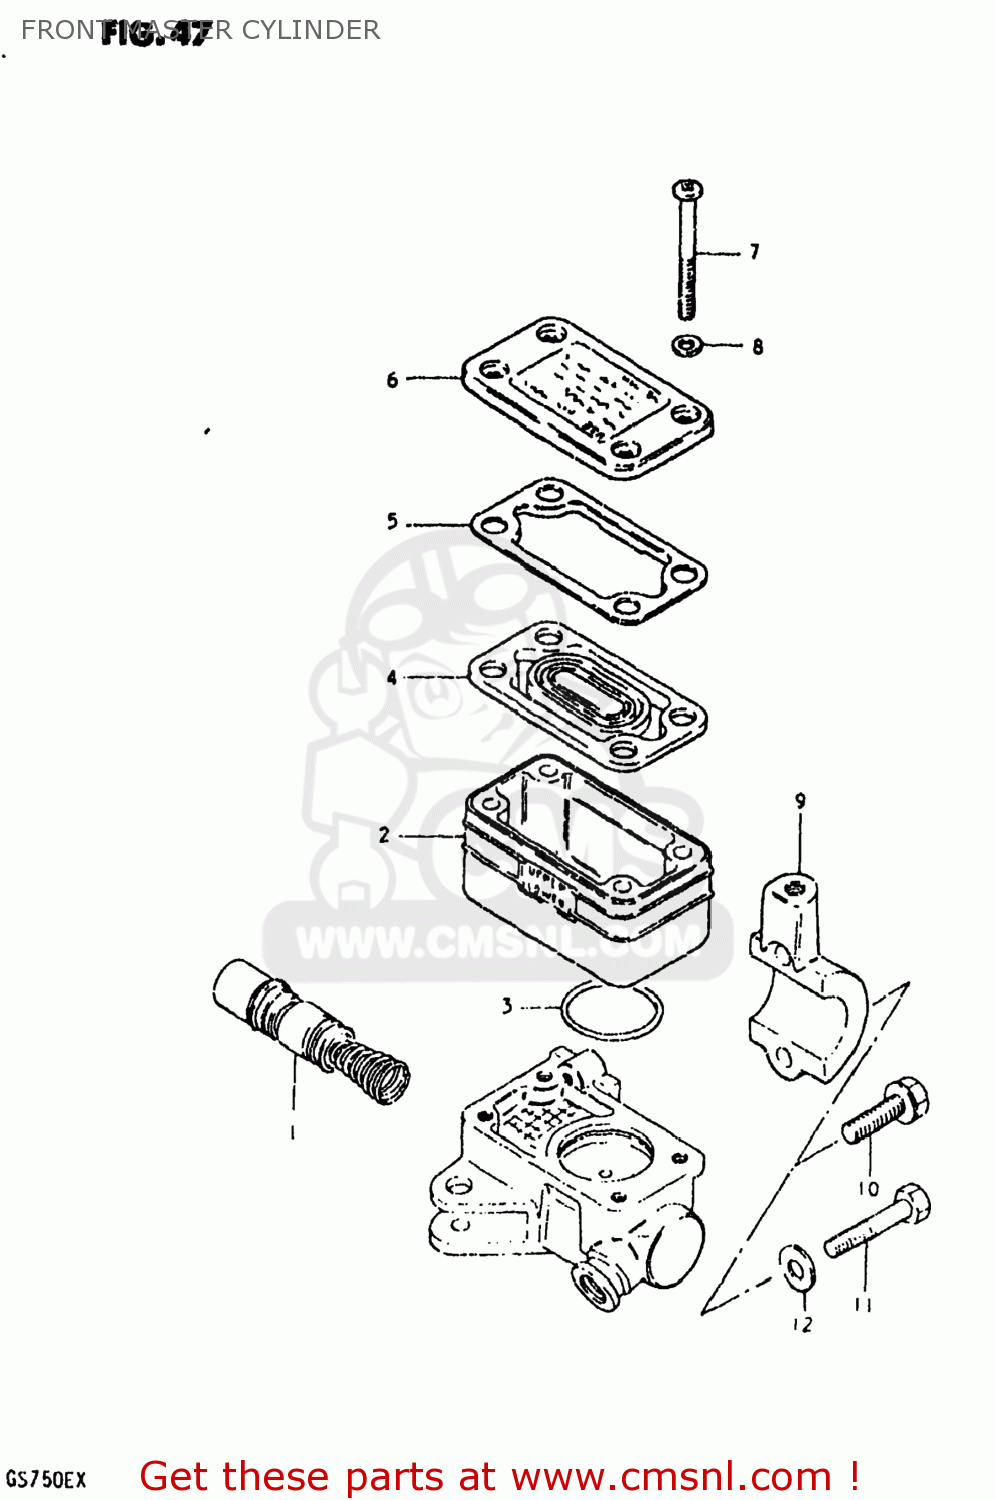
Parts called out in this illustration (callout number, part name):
1	PISTON & CUP SET
2	RESERVOIR
3	O RING
4	DIAPHRAGM
5	PLATE,DIAPHRAGM
6	CAP
7	SCREW
8	WASHER
9	HOLDER
10	BOLT,MASTER CYLINDER H
11	BOLT
12	WASHER
